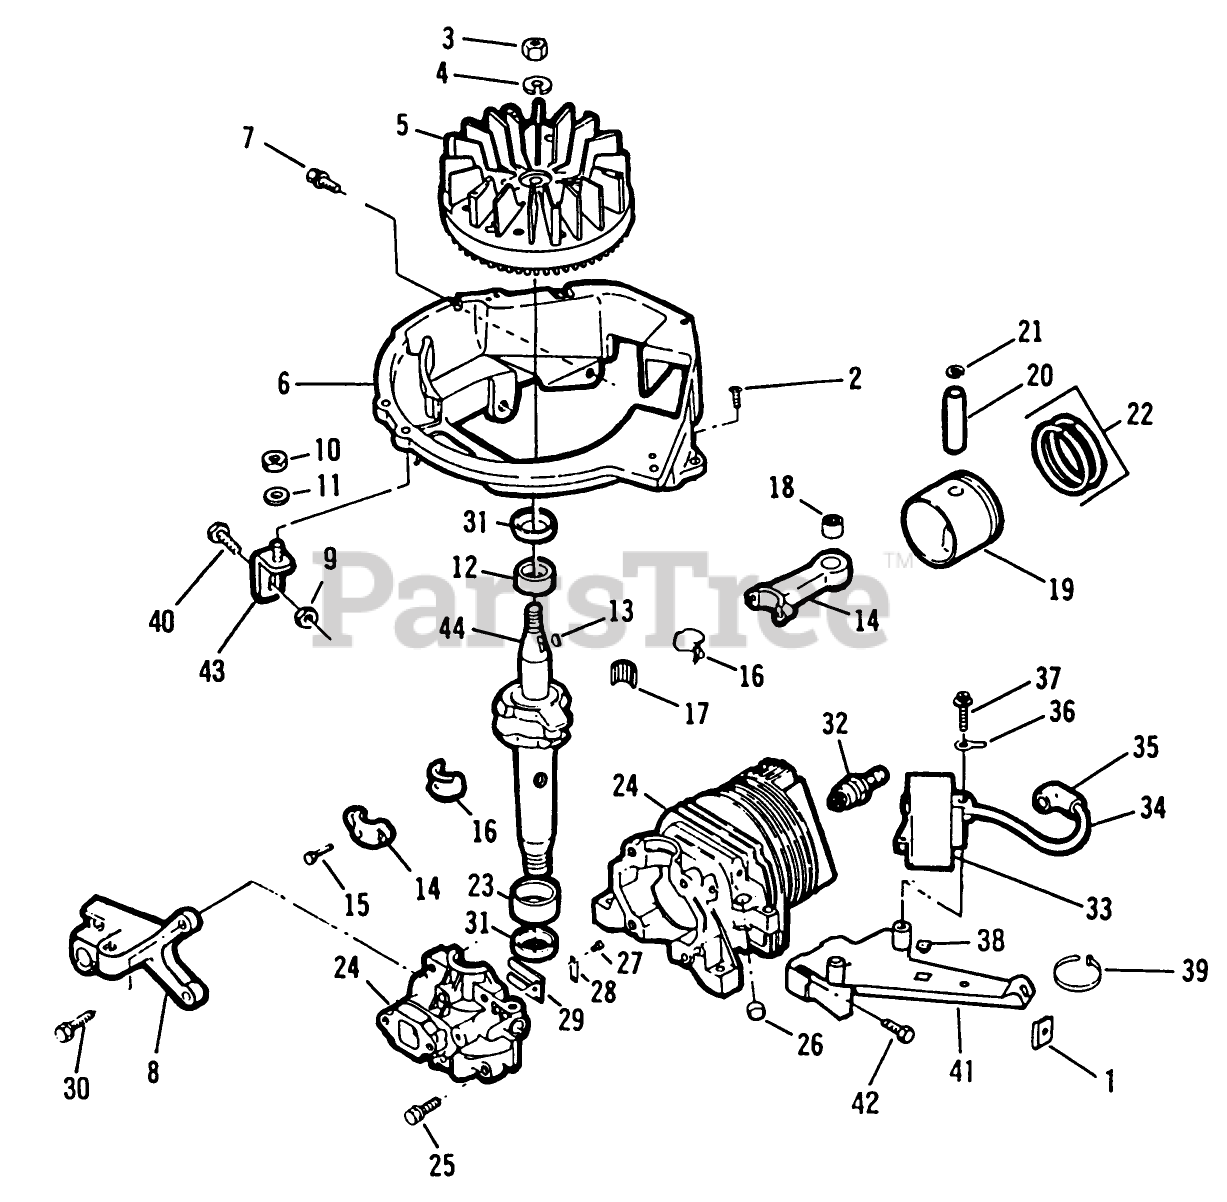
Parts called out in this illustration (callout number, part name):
1	NUT-SPEED
2	SCREW F
3	NUT
5	FLYWHEEL ASSY F
7	SCREW-SEMS
8	BRACKET-BRAKE F
9	NUT-LOCK F
10	LOCKNUT E
11	WASHER S
12	BEARING V
13	KEY
15	SCREW-HSH
16	LINER ASM
17	BEARING-NEEDLE
18	BEARING AY F
21	RING-RETAINING
23	BEARING V
25	SCREW S
26	PLUG-CORE VF
27	SCREW-HH
28	PLATE-BACKUP, REED
30	SCREW
31	SEAL-OIL
34	HT LEAD&COVER XEV
36	TERMINAL S
38	NUT-CLIP
40	BOLT F
43	BRACE AY F
